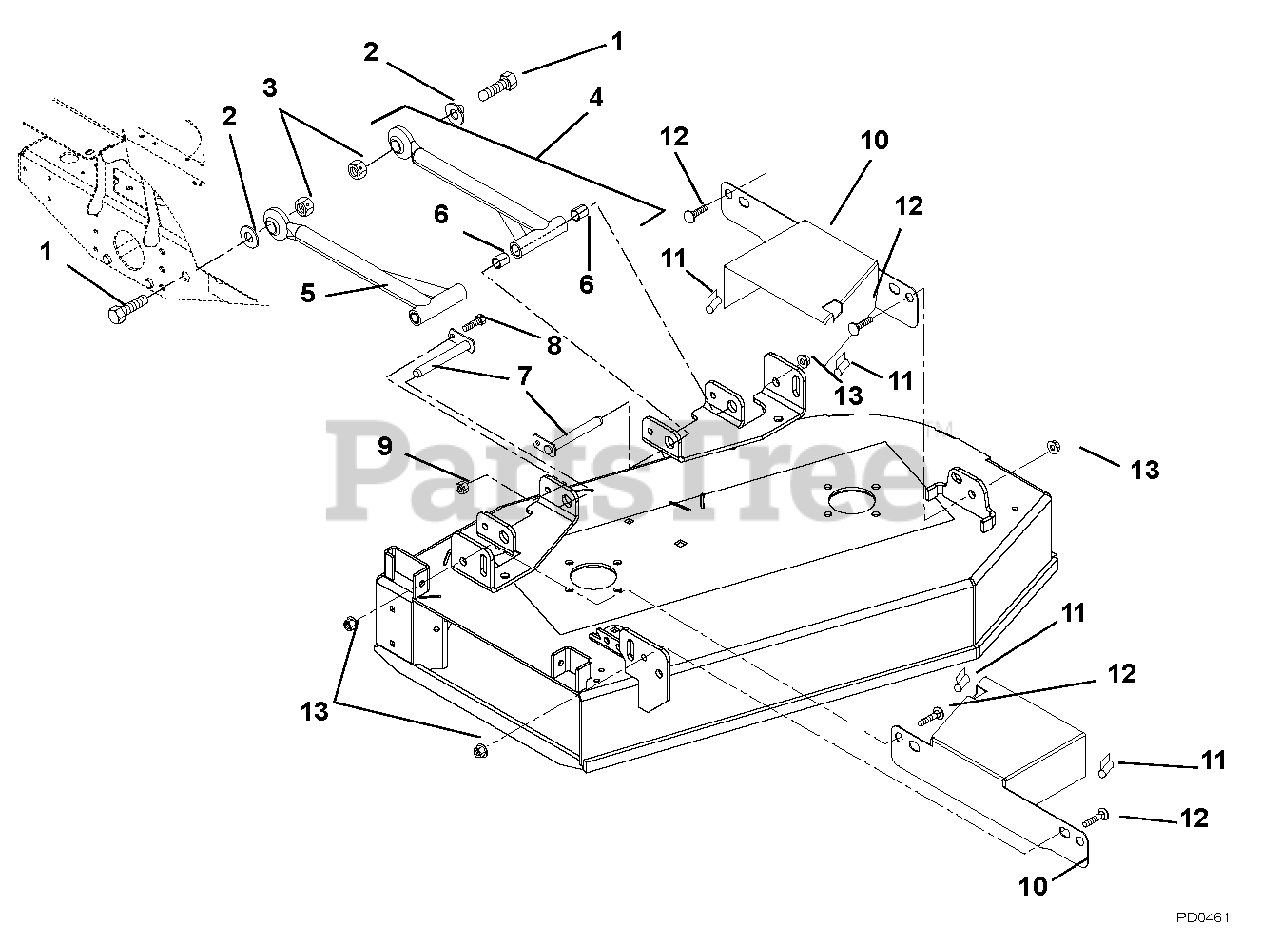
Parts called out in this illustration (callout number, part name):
1	Bolt, Hex .875-9 x 3.00
2	Bushing, Sleeve .875 x 1.25 x .531
3	Nut, Locking Center .875-9
4	Assembly, Mower Mounting (Includes Items 5 and 6)
5	Arm, Mower Mounting
6	Bearing, .75 x .875 x 1.00
7	Weldment, Mower Mounting Pin
8	Bolt, Hex .38-16 x 1.00
9	Nut, Nyloc Flange 3/8-16
10	Guard, 34" Belt
11	Seal, Trim-LOK Bulk .06 Bubble
12	Bolt, Round Head Square Neck .50-13 x 1.00 Grade 5
13	Nut, Nyloc Flange .50-13
